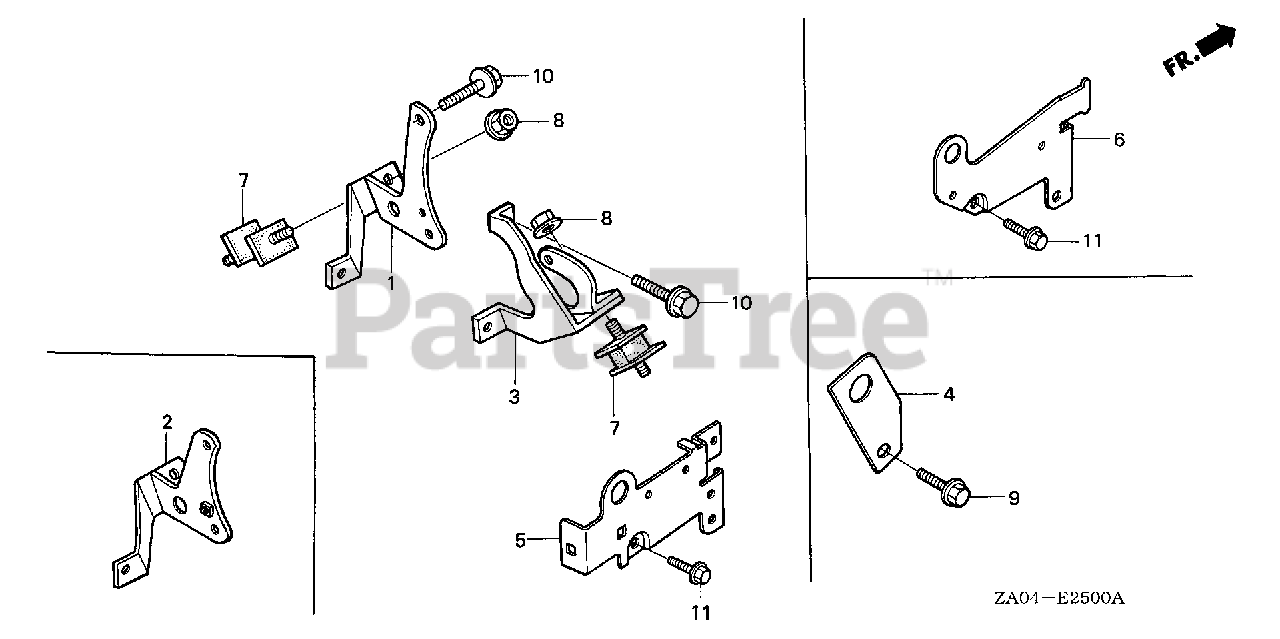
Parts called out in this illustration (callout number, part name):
2	STAY, ENGINE MOUNTING
3	STAY, L. ENGINE MOUNTING
5	HOOK, ENGINE
7	RUBBER, ENGINE SETTING
8	NUT, FLANGE (10MM)
10	BOLT, FLANGE (8X20) Use up to Engine SN 1609606.
11	BOLT, FLANGE (8X20) Use up to Engine SN 1609606.
